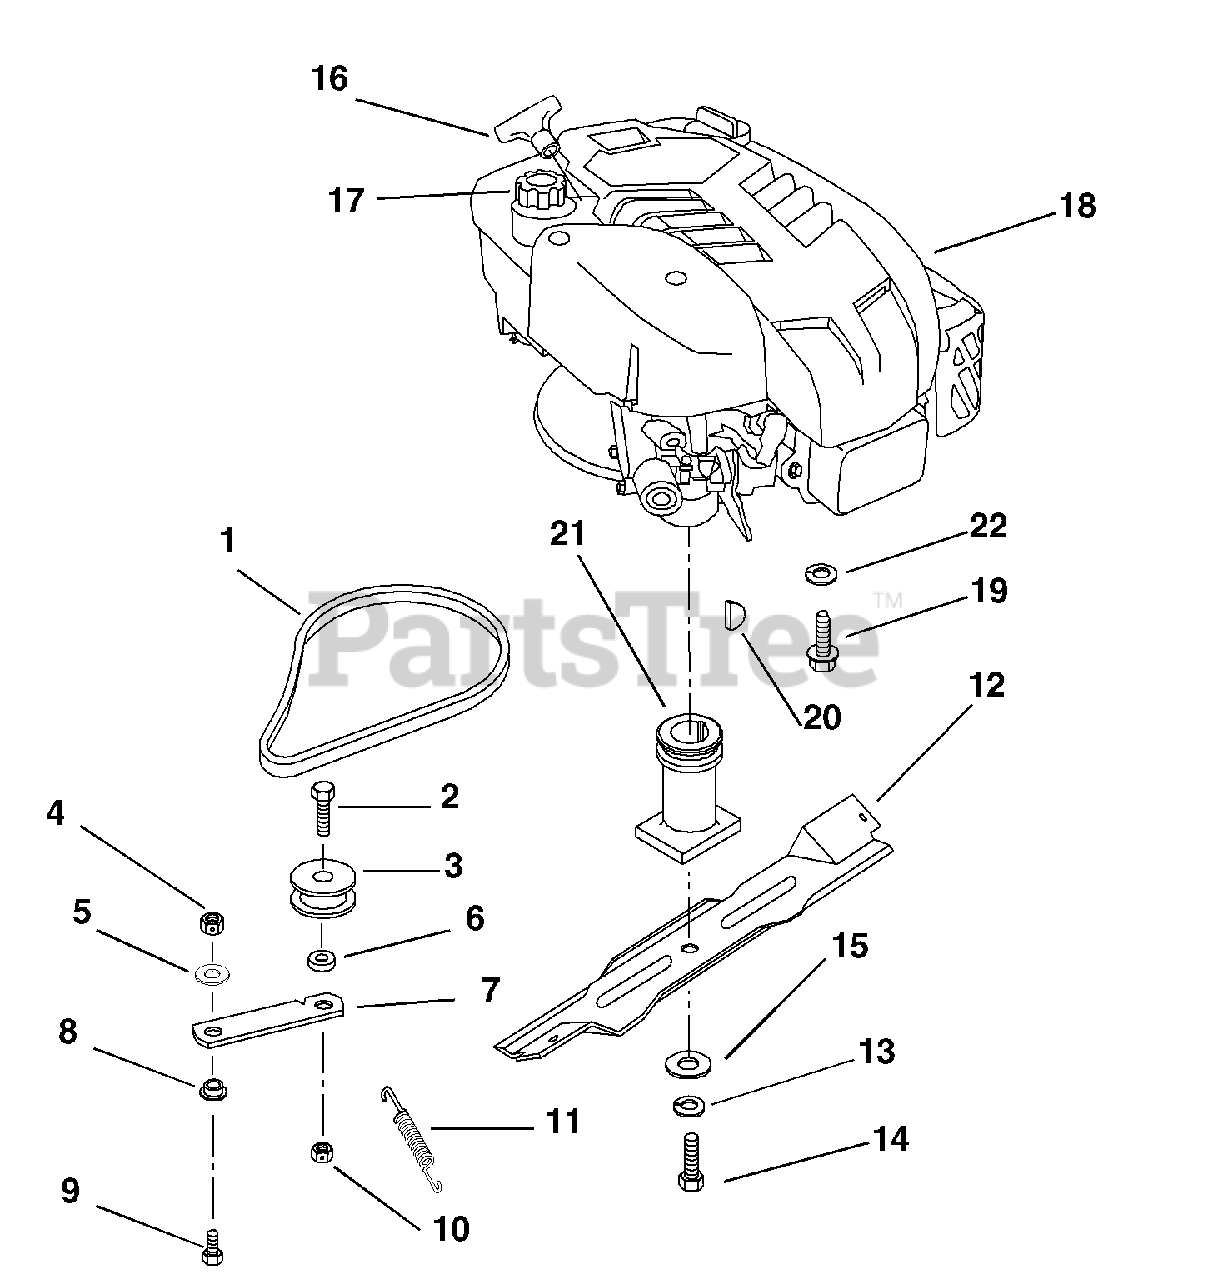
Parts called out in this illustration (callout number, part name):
1	V-BELT, 3L-COGGED
2	@BLT-HEX .44-14X1.25 GR5 YWZC
3	IDLER-FLAT 1.75 X .47
4	@NUT-LK-CTR .31-18 YWZC
5	WSHR-FL-STL .323X.625X.062 YWZ
6	SPACER .52 X .45 X .34
7	IDLER ARM
8	BSHG-FLG .325X.501X.250X1.120
9	@BLT-HEX .31-18X.75 GR5 YWZC
10	@NUT-LK-CTR .44-14 YWZC
11	SG-TENS .043X.44X3.31 WLD 5.8
12	BLADE LM 21 IN
13	@WSHR-LK .38X.094 REG YWZC
14	BLT-HEX .38-24X2.0 YWZC
15	WSHR-FL-STL .390X1.5X.125 YWZC
16	HANDLE, RECOIL START
17	FUEL CAP
18	ENGINE, B&S 6.75HP INTEK SCOTT
19	@SCR-TAP .38-16X1.00 HWH TR YZ
20	KEY-WDRF .156X.625X.25 SAE 6
21	PLZ READ SERVICE LETTER #L-429
22	WSHR-LK .312X.097 HVY YWZC
